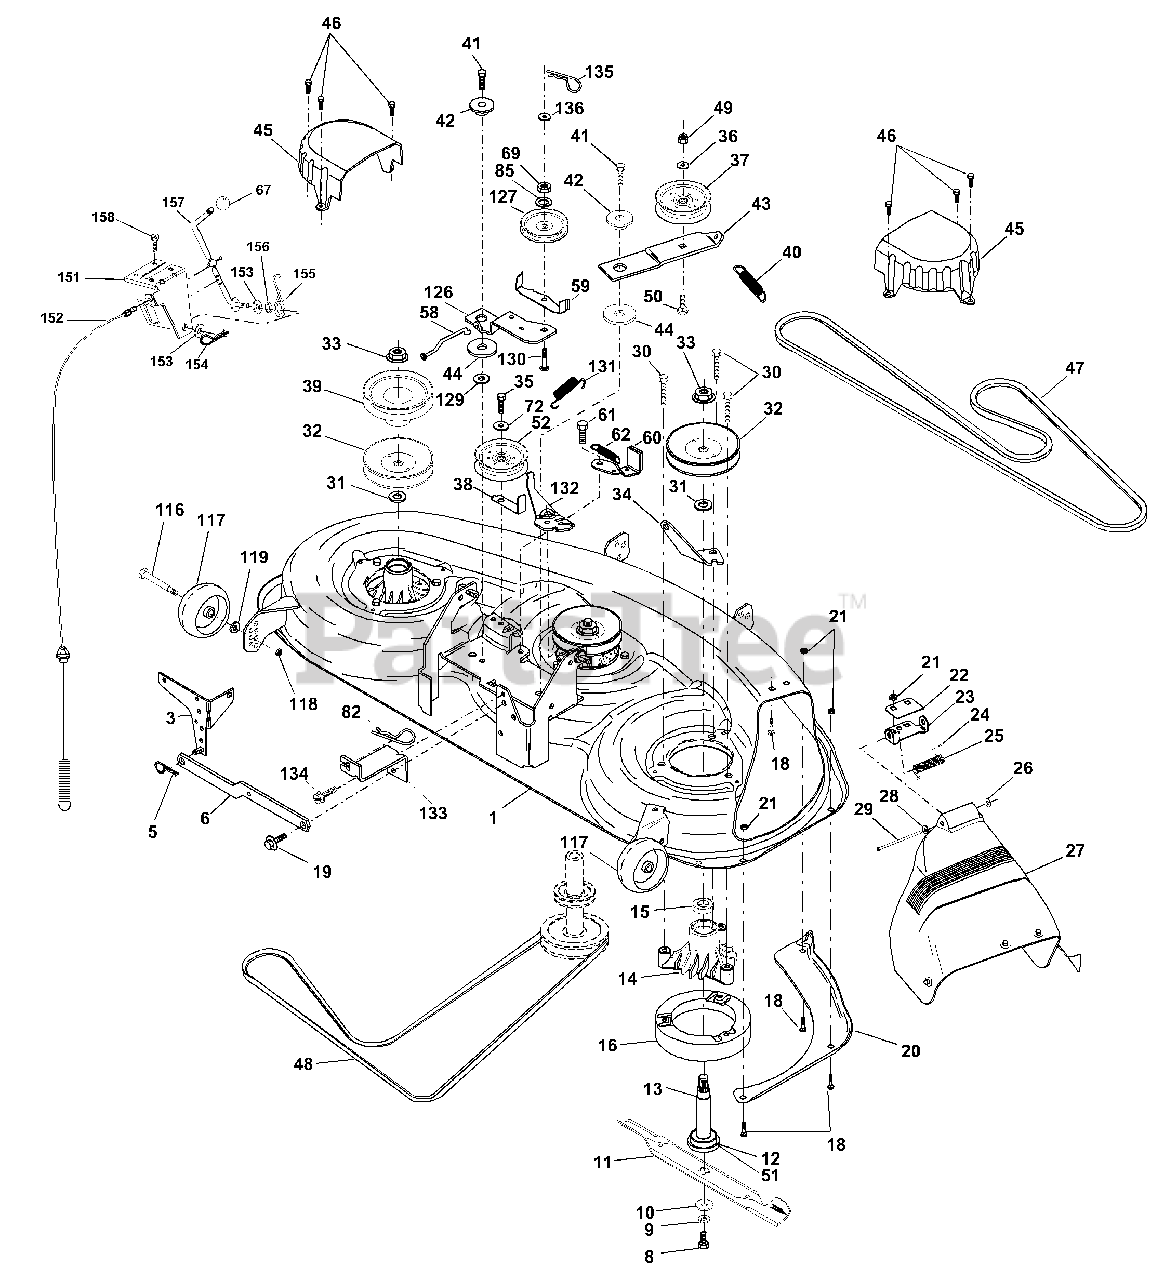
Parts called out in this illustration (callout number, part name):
1	Deck Asm., Mower 46"
3	Bracket Asm., Sway Bar
5	Retainer Spring
6	Arm, Suspension, Rear (Sway Bar)
8	Bolt, Patched 3/8-24 x 1-1/4 Gr. 8
9	Washer, Lock Hvy., Unplated 3/8
10	Washer, Hard Blade, Mower Vented
11	Blade, 46" Mower Deck
12	Bearing, Ball, Mandrel #6204
13	Shaft Asm. w/Lower Bearing
14	Housing, Mandrel
15	Bearing, Ball, Mandrel
16	Stripper, Mower Round
18	Bolt, Carriage 5/16-18 x 5/8
19	Bolt, Hex Head, Shoulder 5/16-18
20	Baffle, Vortex Mower 46"
21	Nut, Crownlock 5/16-18 UNC
22	Stiffiner, Bracket
23	Bracket, Deflector
24	Cap, Sleeve
25	Spring, Torsion, Deflector
26	Nut, Push
27	Shield, Deflector Mower
28	Washer 11/32 x 5/8 x 16 Ga.
29	Rod, Hinge
30	Screw Thd Rolling Washer Head
31	Washer, Spacer Mower Vented
32	Pulley, Mandrel
33	Nut, Flg. Top Lock Cntr. 9/16
34	Anchor, Spring Deck 46"
35	Screw, Thdroll 3/8-16 x 1-3/4 Tytt
36	Washer 13/32 x 13/16 x 16 Ga.
37	Pulley, Idler, Flat
38	Keeper, Belt, Idler
39	Pulley, Idler, Driven
40	Spring, Secondary 44/46/50 Vent
41	Screw, Thdroll 3/8-16 x 1-1/4
42	Spacer, Retainer
43	Arm, Idler Secondary
44	Washer,Hardened
45	Cover, Mandrel Deck
46	Screw, Thdroll. 1/4-20 x 5/8
47	V-Belt, Mower, Secondary
48	V-Belt, Mower, Primary
49	Nut, Crownlock 3/8-16 UNC
50	Bolt, Carriage 3/8-16 x 1-1/2 Gr. 5
51	Washer, Felt
52	Pulley, Idler, Flat
58	Rod Brake 46"
59	Guide, Belt 46" Mower
60	Arm Asm. Brake 46"
61	Bolt, Shoulder 5/16-18 Type TT
62	Spring Return
67	Knob Rd 3/8-16 Plstc hds Blk
69	Nut, Hex Jam 3/8-16 Unc
72	Washer 13/32 x 13/16 x 16 Ga.
82	Retainer Spring 1"
85	Washer, Lock Hvy Hlcl Spr 3/8
116	Bolt, Shoulder
117	Gauge Wheel
118	Nut, Centerlock 3/8-16 UNC
119	Washer 3/8 x 7/8 x 14 Ga.
126	Arm, Idler, Deck 46" Mech.
127	Pulley, Idler, V-Groove Dim. 4.25
129	Washer 13/32 x 2-3/8 x 8 Ga.
130	Bolt Carriage Idler
131	Spring Return Idler
132	Arm Spring Brake Mower
133	Bracket Anchor Cable 46"
134	Screw Thdrol 5/16-18 x 3/4
135	Retainer Spring Yellow
136	Washer 9/32 x 3/4 x 16 Ga
151	Bracket Clutch Cable
152	Clutch Cable 38"/46"
153	Washer Flat 3/8" Type B
154	Spring Retainer
155	Spring Retention
156	Spacer Clutch Cable
157	Rod Clutch Cable 38"
158	Screw Hex Thd Cut 1/4-20 x 5/8
